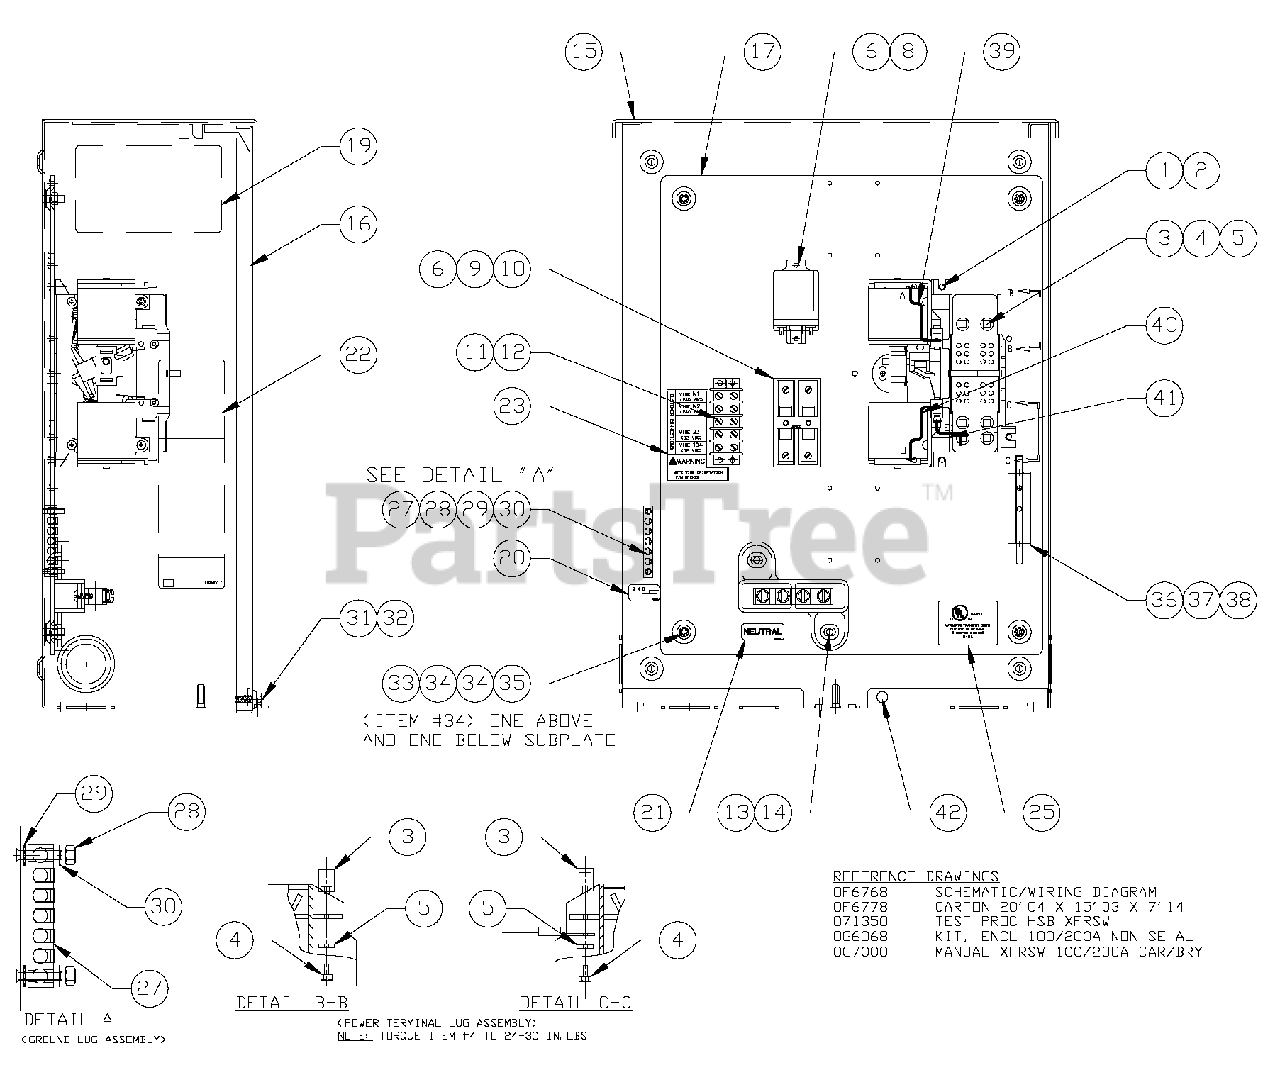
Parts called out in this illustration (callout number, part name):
1	TR SW-HSB 100A 2P 250V
2	SCREW HHTT M5-0.8 X 10 BP
3	LUG SLDLSS 1/0-#14X9/16 AL/CU
4	SCREW, PPHMS 10-32 X 3/8""
5	WASHER, LOCK # 10
6	SCREW HHTT M4-0.7 X 10 BP
8	RELAY PNL 12VDC DPDT
9	FUSEBLOCK 30A 600V 2 POLE
10	FUSE 5A X BUSS HLDR73591
11	BLOCK, TERM 20A 5 X 6
12	RIVET, POP .156 X .67
13	ASS'Y NEUTRAL BLOCK 100A
14	SCREW HHTT M6-1.0 X 12 MM
15	ENCLOSURE, 100/200A TRANSFER SWITCH
16	COVER, TRANSFER SWITCH
17	SUBPLATE, 100/200A XFER SW
19	DECAL, XFER SW NON 100A 120/240
20	DECAL, GROUNDING LUG
21	DECAL, NEUTRAL
22	DECAL, MANUAL 5A FUSE
23	DECAL, TERMINAL STRIP
24	DECAL, TEST SEQUENCE
25	DECAL, UL LIST HSB
26	DECAL, LIVE CIRCUIT ENG/FRN/SPN
27	GROUND BAR (5) 4-14 AWG CONN
28	NUT HEX LOCK M4-0.7 SS NYL INS
29	WASHER SHAKEPROOF EXT #8 STEEL
30	WASHER FLAT M4
31	SCREW HHC 1/4-20 X 1/2 SS
32	WASHER M6 NYLON INT HEX
33	NUT HEX 1/4-20 SS
34	WASHER FLAT 1/4-M6 ZINC
35	WASHER LOCK M6-1/4
36	BRACKET, ARM EXTENDER
37	ARM EXTENDER PIN
38	RIVET POP .156 X .362 AL
41	WIRE-E1
42	NUT TRIC 1/4-20 X .525
